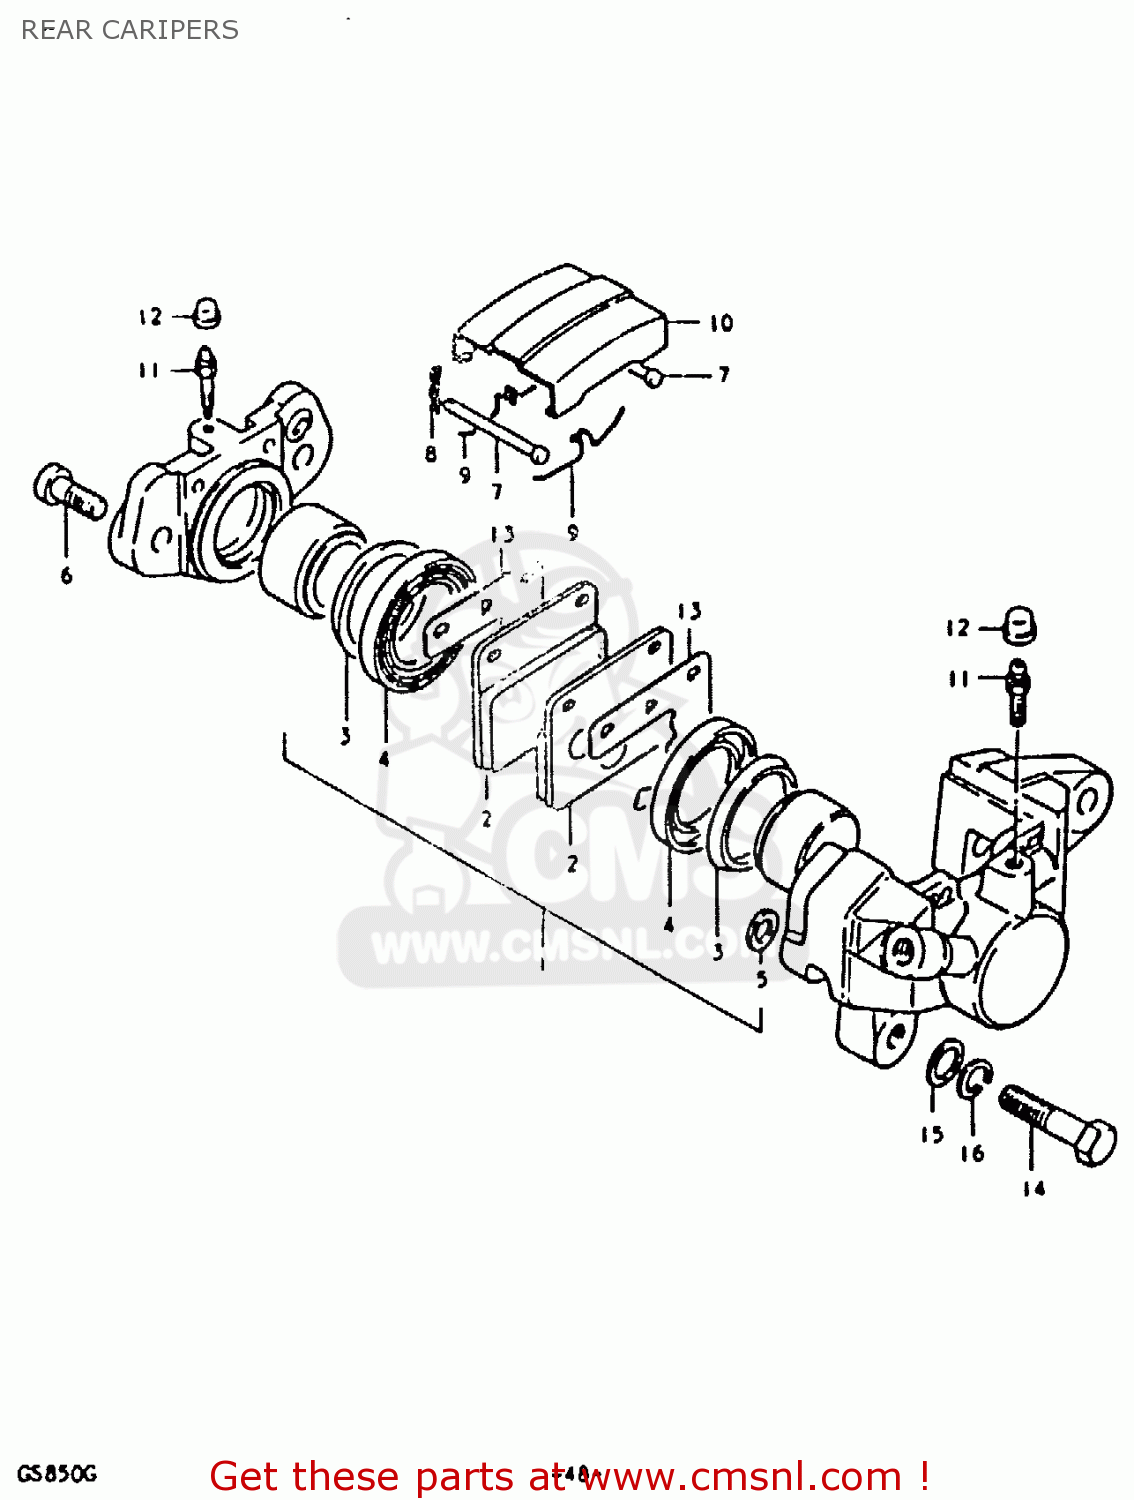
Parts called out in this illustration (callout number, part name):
1	PISTON SET
2	PAD,BRAKE
3	SEAL,PISTON
4	BOOT,PISTON
5	SEAL,PISTON
6	BOLT,HOUSING
7	PIN,PAD
8	CLIP,PAD PIN
9	SPRING
10	COVER,DUST
11	BLEEDER
12	CAP,BREATHER
13	SHIM,RR CALIPER
14	BOLT 10X34
15	WASHER
16	LOCK WASHER
